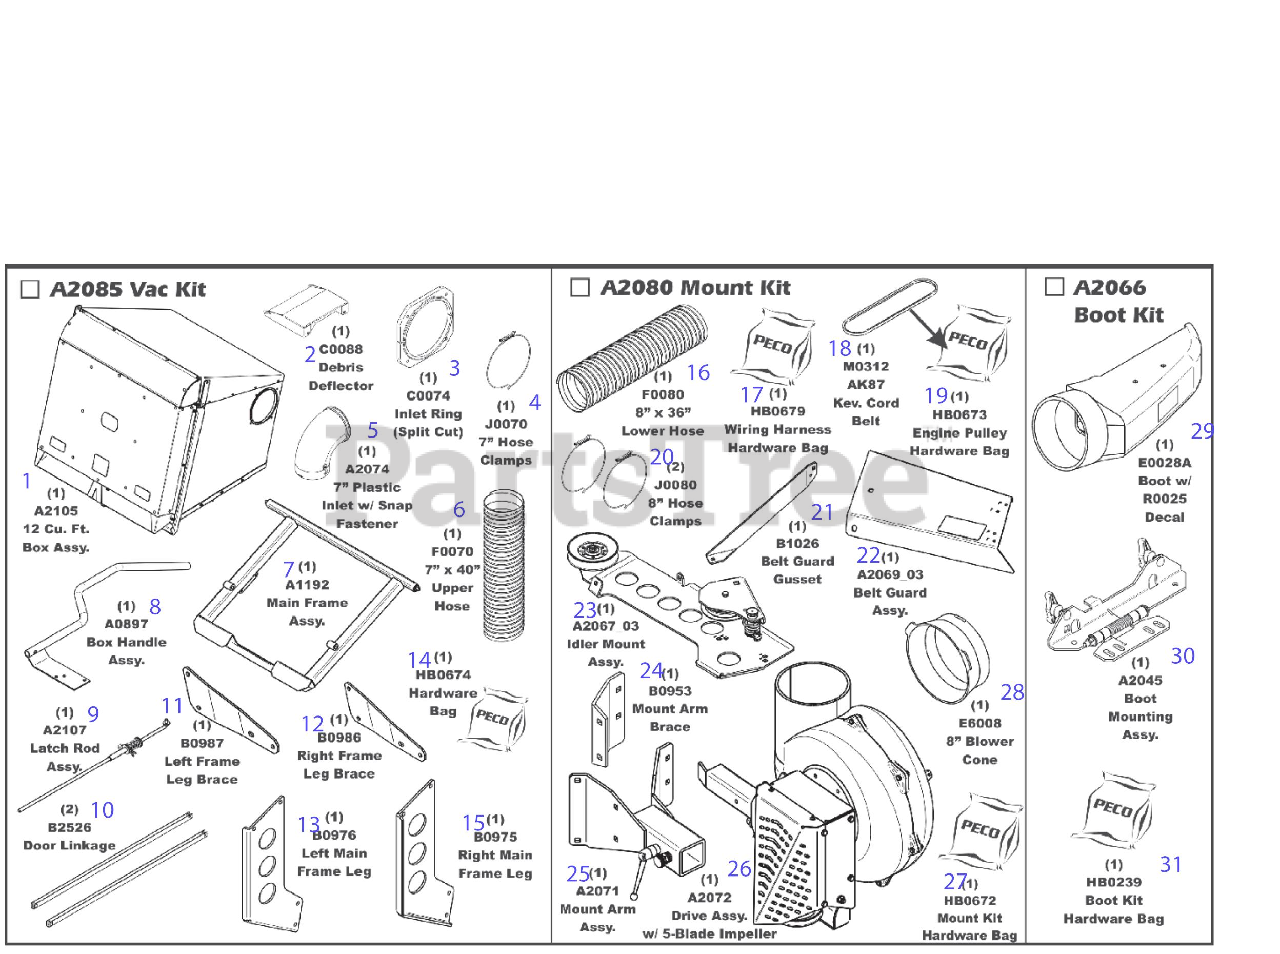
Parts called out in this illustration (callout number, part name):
1	Box Assembly
2	Debris Deflector
3	Inlet Ring (Split Cut)
4	Hose Clamp 7"
5	7" Inlet W/Snap Fastener
6	7" X 26" Upper Hose
7	Main Frame Assembl
8	Box Handle Assembly
9	Latch Rod Assembly
10	Linkage Rod
11	Left Frame Leg Brace
12	Right Frame Leg Brace
13	Left Main Frame Leg
14	Hardware Bag
15	Right Main Frame Leg
16	8" X 36" Lower Hose
17	Wiring Harness Hardware Bag
18	Ak87 Kevlar Cord Belt
19	Engine Pulley Hardware Bag
20	Hose Clamp 8"
21	Belt Guard Guesset
22	Belt Guard Assembly
23	Idler Mount Assembly
24	Mount Arm Brace
25	Mount Arm Assembly
26	Drive Assembly W/5 Blade Impeller
27	Mount Kit Hardware Bag
28	8" Blower Cone
29	Boot With Decals
30	Boot Mounting Assembly
31	Boot Kit Hardware Bag
